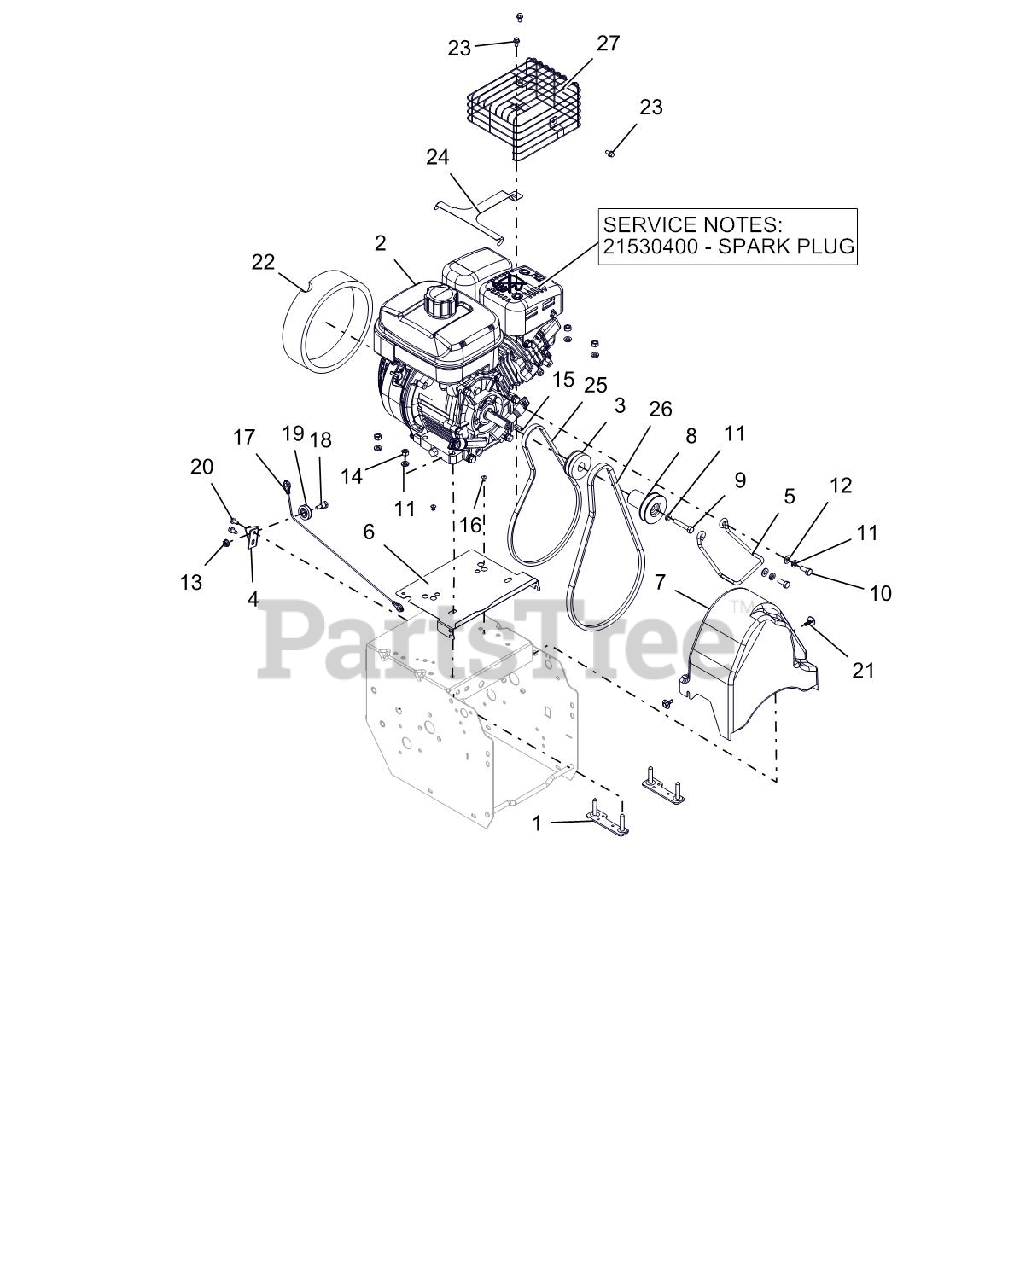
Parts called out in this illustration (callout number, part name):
1	STRAP, ENGINE BOLT-WELDMENT
2	PLUG, SPARK - TEC. SNO-THRO
2	SUBARU EX17 RECOIL ALL-SEASON
3	PULLEY, TRACTION
4	BRACKET, CABLE PULLEY
5	BELT FINGER
6	BAFFLE, COMPACT
7	BELT COVER
8	SHEAVE, AUGER DRIVE
9	@BLT-HEX .31-24X1.75 GR5 YWZC
10	BLT-HEX .31-24X.75 YWZC GR5
11	WSHR-LK .312X.097 HVY YWZC
12	@WSHR-FL-STL.344X.688X.065YWZC
13	@NUT-LK-CTR-FLG .25-20 YWZC
14	@NUT-HEX .31-18 YWZC
15	KEY-SQ .188X.75X.188
16	RVT-POP .187 YZ
17	CABLE, LOWER TRACTION (CMPCT)
18	BOLT, SHLDR-.375X.375X.25-20
19	PULLEY, CABLE
20	SCR-TAP .25-20X.50 HWH TR YWZ
21	SCR-TAP .25-20X.5 CAPTIVE
22	FOAM COVER, RECOIL-SUBARU
23	BLT-SERHFWH M6X1.0X12 8.8 CZ
24	GUARD, SNOW-SUBARU EX17
25	V-BELT, 3L-WRAPPED
26	V-BELT, HA-RAW EDGE
27	GUARD,MUFFLER,SUB 20A-37303-11
